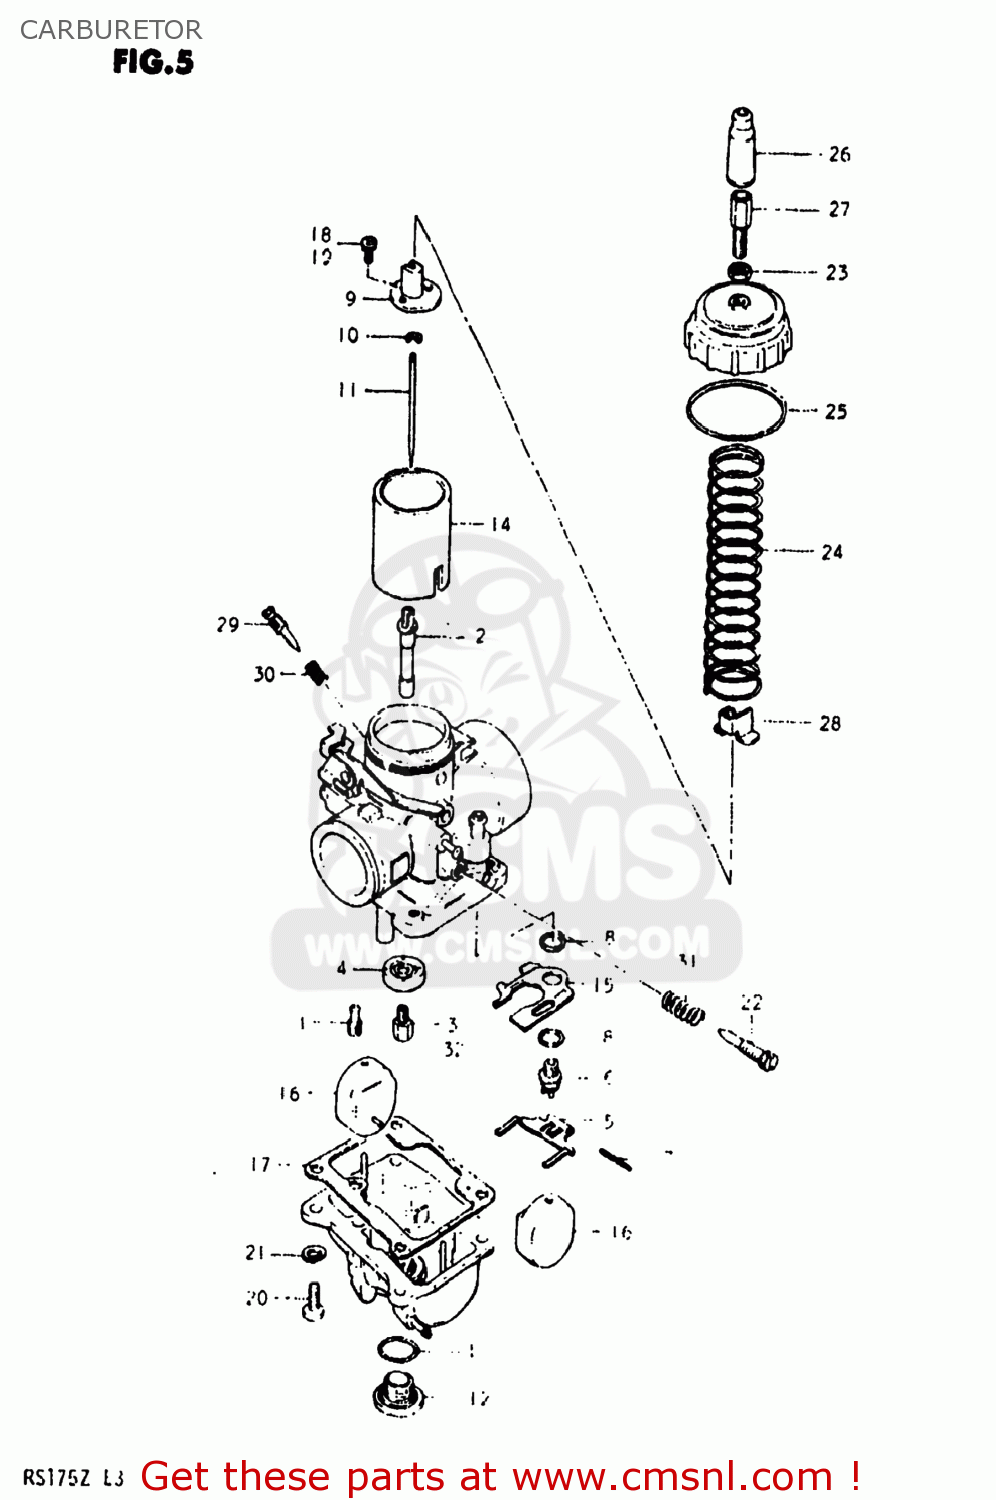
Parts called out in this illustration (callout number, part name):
1	JET
2	JET,NEEDLE
3	JET
4	RING,MAIN JET FIXING
5	ARM,FLOAT
6	VALVE ASSY,NEEDLE
7	PIN,FLOAT
8	GASKET,MAIN JET HOLDER (NAS)
9	CONNECTOR
10	CLIP
11	NEEDLE JET
12	PLUG
13	GASKET,DRAIN PLUG
14	VALVE,THROTTLE
15	PLATE
16	FLOAT
17	GASKET,FLOAT CAHMBER (NAS)
18	SCREW
19	LOCK WASHER
20	SCREW
21	LOCK WASHER
22	ADJUSTER
23	NUT
24	SPRING,THROTTLE VALVE RETURN
25	O-RING,MIXING CHAMBER
26	CAP
27	ADJUSTER,CABLE
28	COVER,HOLDER
29	SCREW,PILOT AIR
30	SPRING
31	SPRING,THROTTLE SCREW
32	JET
